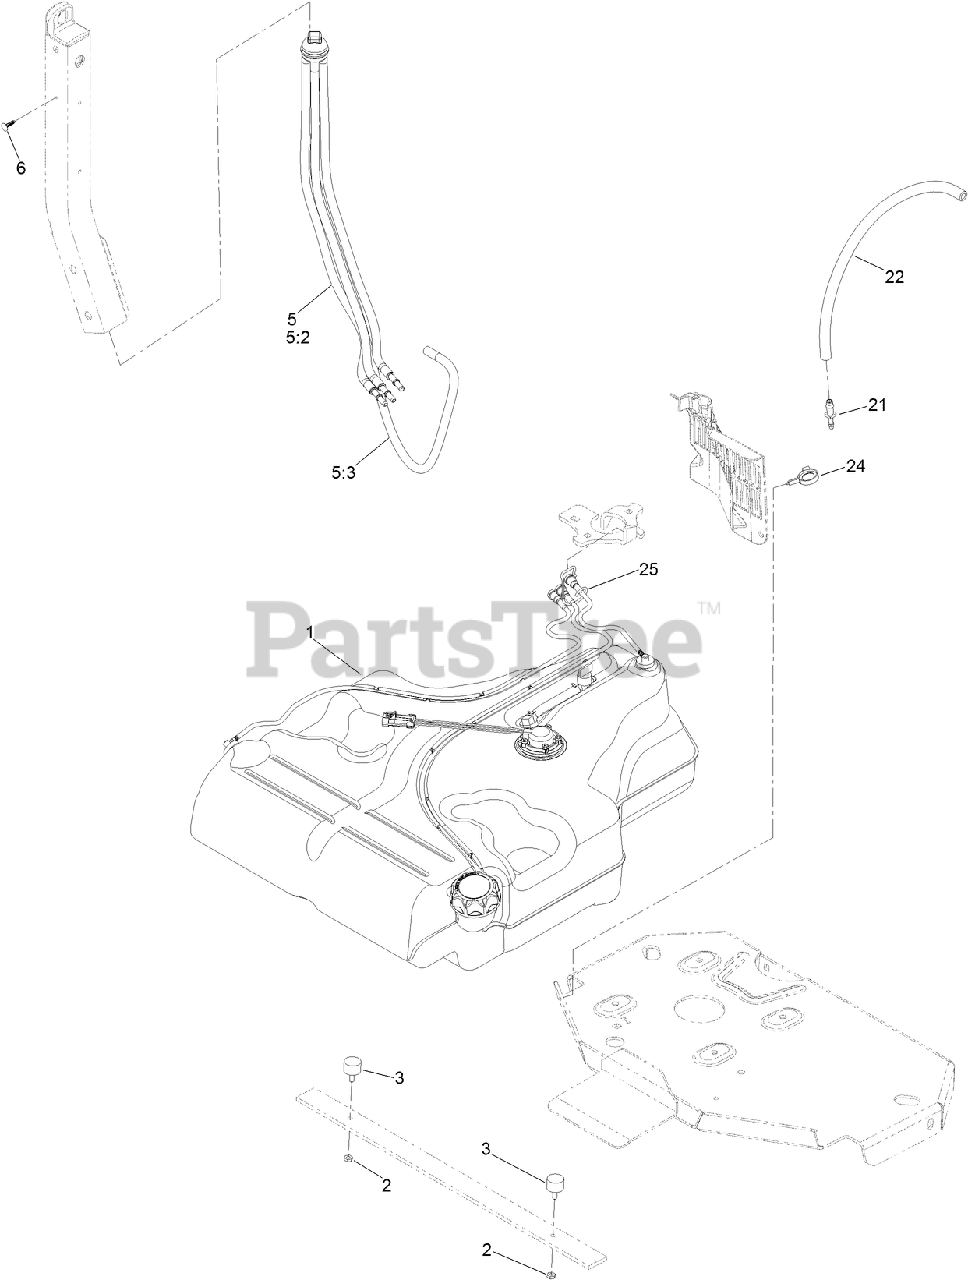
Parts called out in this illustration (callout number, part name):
1	FUEL TANK ASM
2	NUT-JAM
3	BUMPER-RUBBER (W/ STUD)
5	FUEL MANIFOLD VENT ASM
5:2	HOSE-FUEL
5:3	HOSE-FUEL
6	PLUG-PLASTIC
21	FITTING-STRAIGHT
22	HOSE-FUEL
24	CLAMP-HOSE
25	RETAINER-LINE, VAPOR
